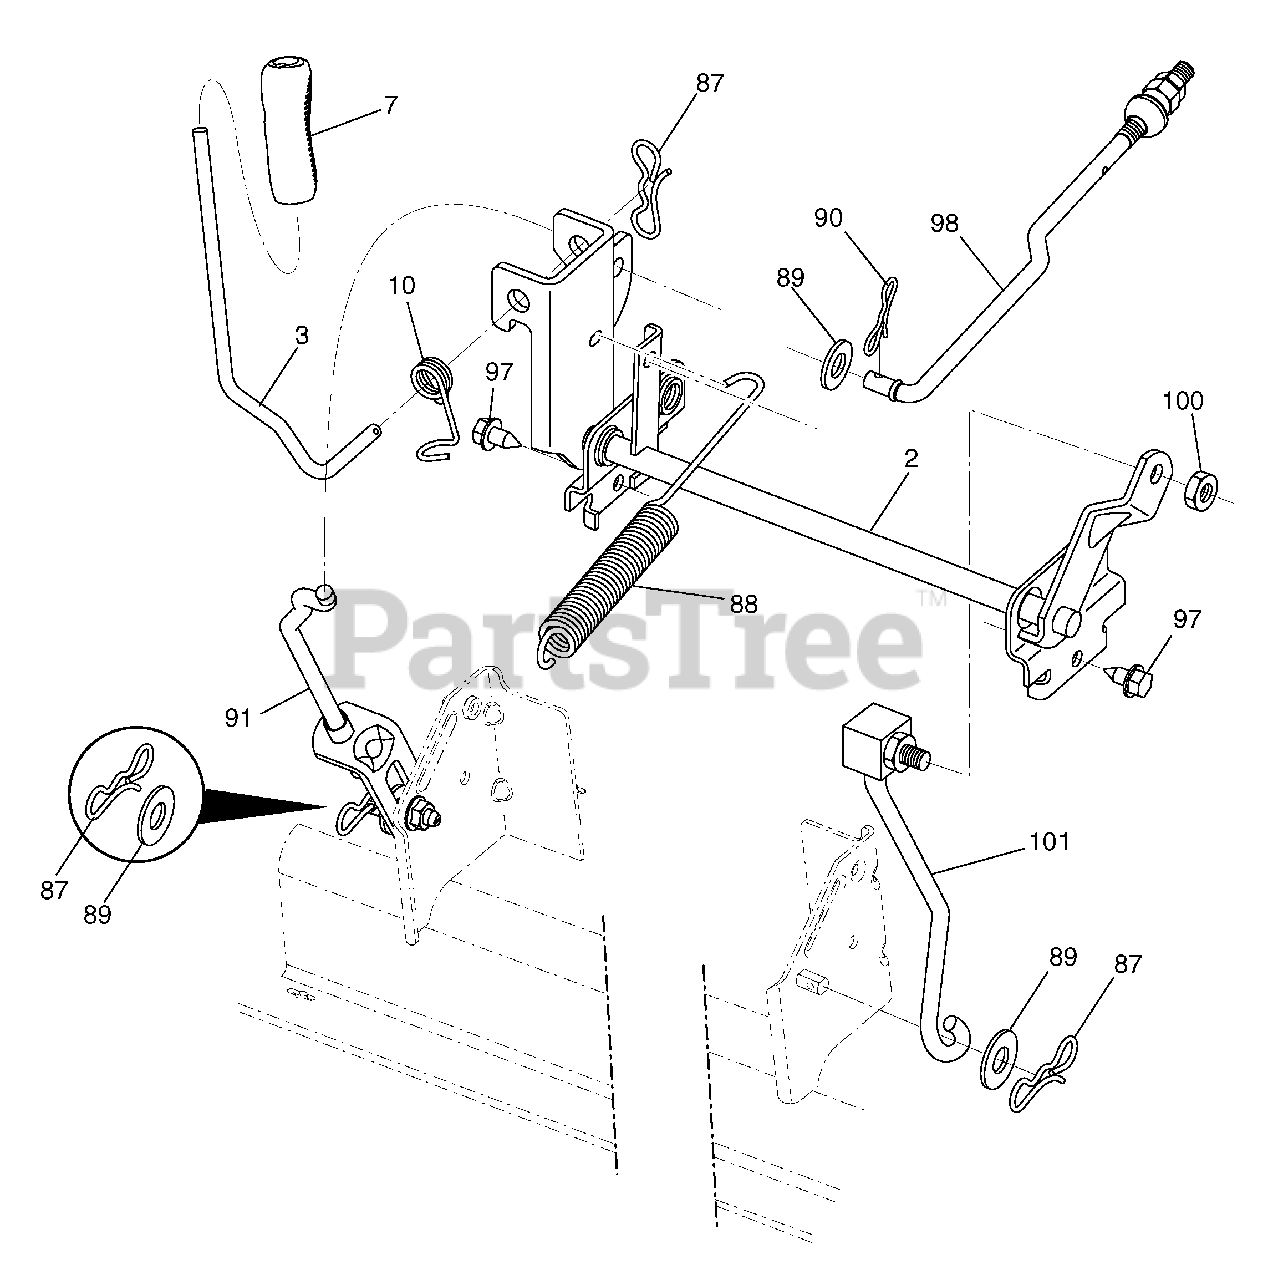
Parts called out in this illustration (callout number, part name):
2	Shaft Asm., Lift
3	Lever Asm., Lift RH
7	Grip, Lever
10	Spring Torsion
87	Pin Cotter 7/16 Bow Tie Lock
88	Spring Lift Assist
89	Washer Clear Zinc
90	Pin Cotter 5/16 Bow Tie Lock
91	Link Asm. Lift Rear
97	Screw 3/8-16 x .75 Smgml Tap/R.Z
98	Link Lift Susp. Front Mower
100	Nut Centerlock 3/8-16 unc
101	Link Asm. Lift Fixed
